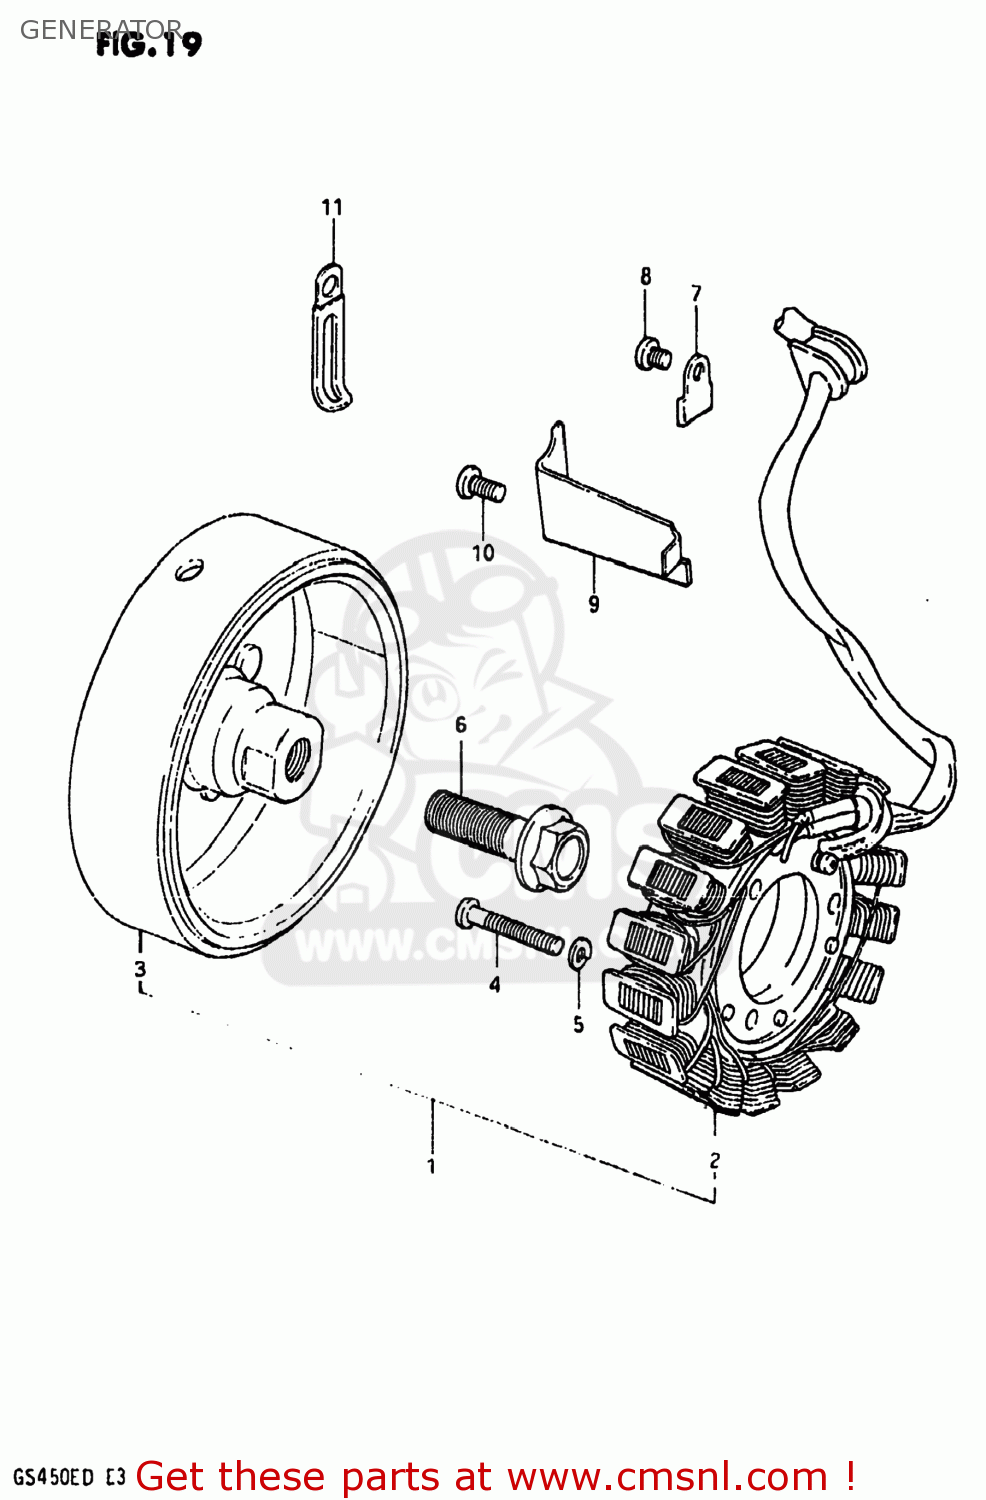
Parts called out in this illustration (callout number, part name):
1	GENERATOR ASSEMBLY
2	STATOR ASSEMBLY
3	ROTOR ASSEMBLY
4	SCREW
5	LOCK WASHER
6	BOLT(12X40)
7	CLAMP,GENERATOR LEAD WIRE
8	SCREW
9	CLAMP,GENERATOR LEAD WIRE
10	SCREW
11	CLAMP L:35
